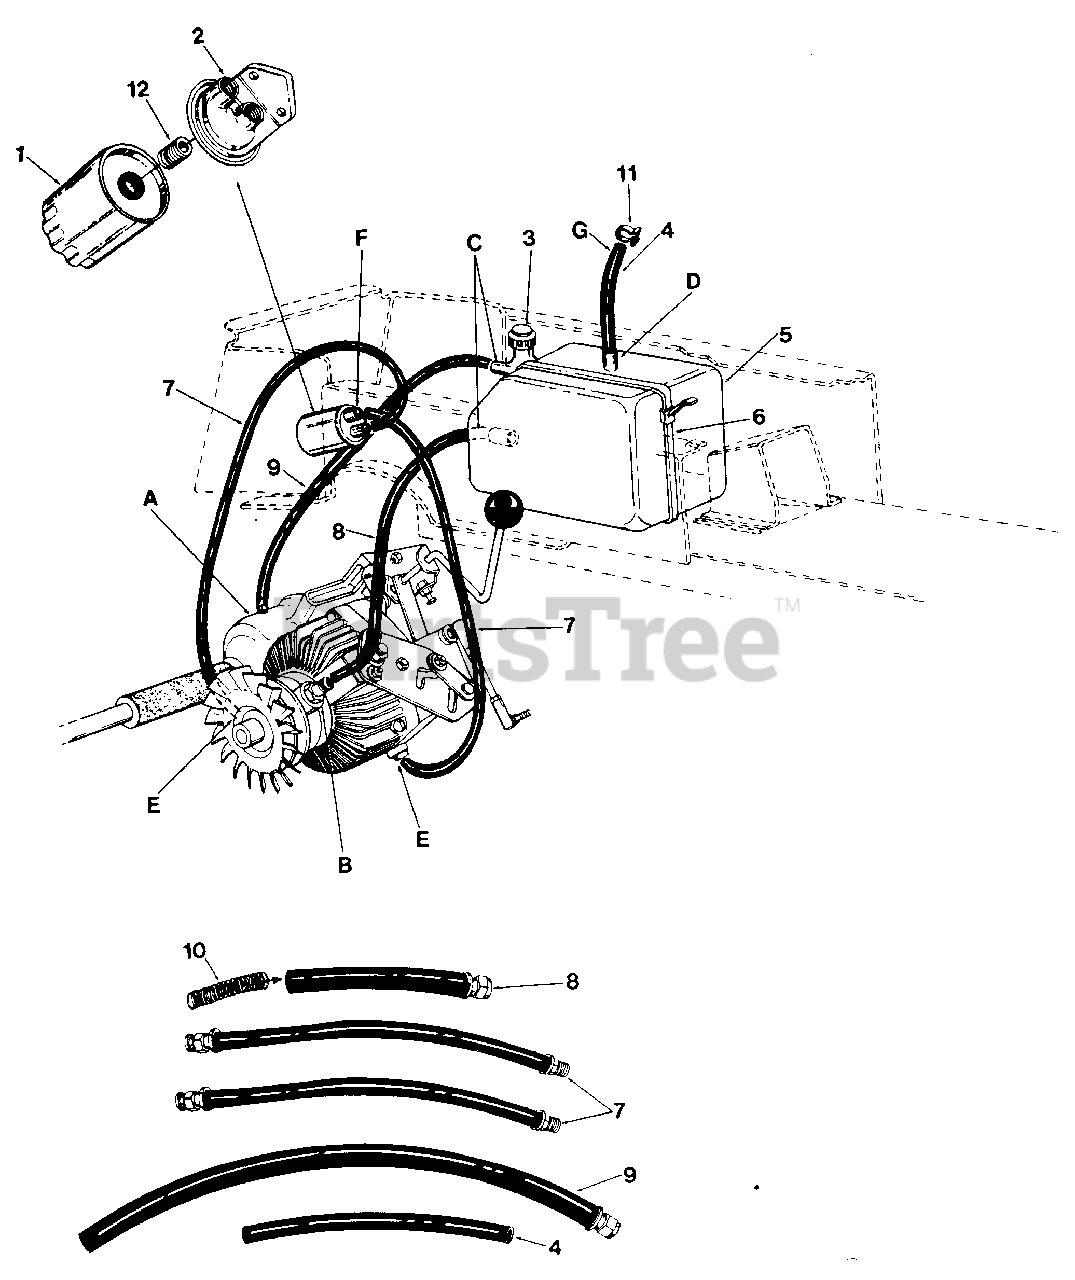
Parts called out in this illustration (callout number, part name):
1	Oil Filter
2	Filter Base
3	Oil ReseNoir Cap
4	Gas Line-13" Lg.
5	Oil Reservoir
6	Cable Tie 34.25" Lg.
7	Hose Ass'y. 3/8" I.D. x 16.5" Lg.
8	Hose Ass'y. 5/8" I.D. x 9" Lg.
9	Hose Ass'y. 1/2" I.D.
11	Wire Retainer
12	Plug Expansion 13/16
